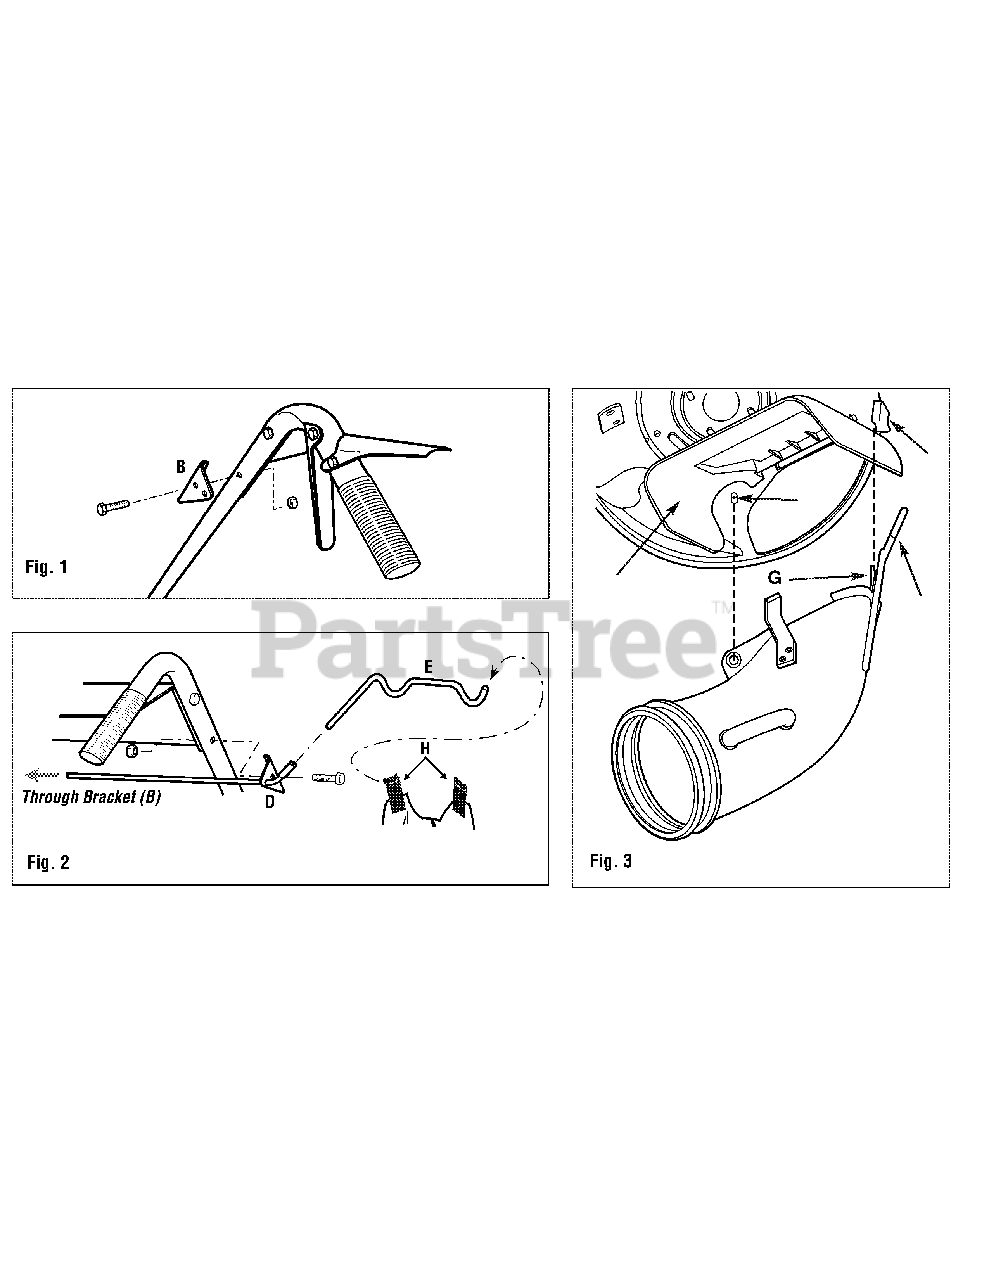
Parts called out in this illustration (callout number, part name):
B	Bracket (Bag Hanger)
D	Support Assembly
E	Bag Hanger
G	Chute Assembly
H	Grass Bag Kit
